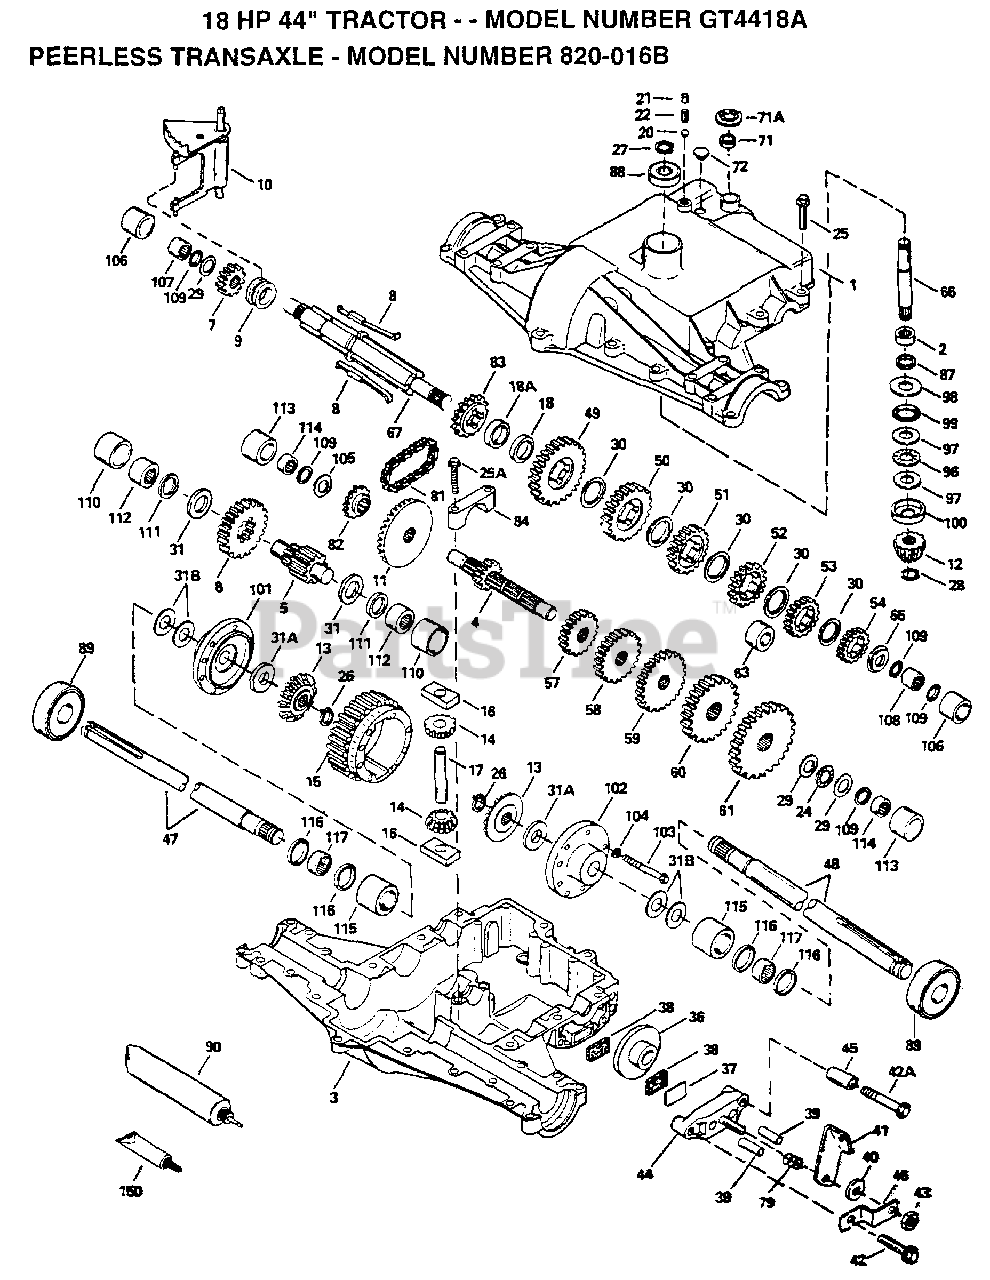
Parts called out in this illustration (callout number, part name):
1	COVER TRANSAXLE
2	BEARING NEEDLE
3	CASE TRANSAXLE
4	SHAFT COUNTER
5	SHAFT, OUTPUT, 9T
6	GEAR, OUTPUT, 35T
7	GEAR, SPUR, 15T
9	COLLAR SHIFT
10	ROD AND FORK ASSY SHIFT
11	GEAR BEVEL, 33T
12	BEVEL PINION, 13T
14	PINION, 10T
15	GEAR, RING, 31T
16	BLOCK DRIVE
18	SPACER, .350/.340 THICK
18A	SPACER, .276/.268 THICK
20	BALL STEEL, 5/16" DIA.
21	SCREW, 3/8-16 X 3/8"
24	THRUST BEARING
25	SCREW HEX HD 5/16-18 X 1-1/4
25A	SCREW, 1/4-20 X 1-1/4
28	RETAINING RING
29	WASHER THRUST
30	WASHER THRUST
31	WASHER THRUST
31B	WASHER THRUST
37	PLATE BRAKE PAD
41	LEVER BRAKE
42	SCREW, 1/4-20 X 1-1/4
42A	SCREW, 1/4-20 X 2-1/4
43	LOCKNUT 5/16-24
44	HOLDER BRAKE PAD
46	BRKT BRAKE LEVER
47	AXLE, 12-5/16" LONG
48	AXLE, 16-3/16" LONG
49	GEAR, SPUR, 41T
50	GEAR, SPUR, 35T
51	GEAR, SPUR, 30T
52	GEAR, SPUR, 25T
53	GEAR, SPUR, 22T
54	GEAR, SPUR, 19T
57	GEAR, SPUR, 15T
58	GEAR, SPUR, 20T
59	GEAR, SPUR, 25T
60	GEAR, SPUR, 28T
61	GEAR, SPUR, 31T
66	SHAFT INPUT
67	SHAFT BRAKE
71	SEAL SQUARE CUT
72	PLUG, THRDED, 9/16-18
81	CHAIN, ROLLER
82	SPROCKET 9T
83	SPROCKET 18T (REV)
84	BEARING CAP
87	OIL SEAL 3/4
88	BEARING BALL
89	BEARING BALL
90	GREASE BENTONITE, 32 OZ.
96	BEARING THRUST
97	WASHER THRUST
100	WASHER CUPPED
101	CARRIER DIFF THREADED HOLES
102	CARRIER DIFF
103	SCREW, 1/4-20 X 2-1/4
104	WASHER LOCK 1/4
107	BEARING NEEDLE
108	BEARING NEEDLE
110	SLEEVE STEPPED
111	RING SQ CUT
112	BEARING NEEDLE CAPPED
113	SLEEVE STEPPED
114	BEARING NEEDLE CAPPED
115	SLEEVE STEPPED
116	RING SQ CUT
117	BEARING NEEDLE
150	GASKET ELIMINATOR
